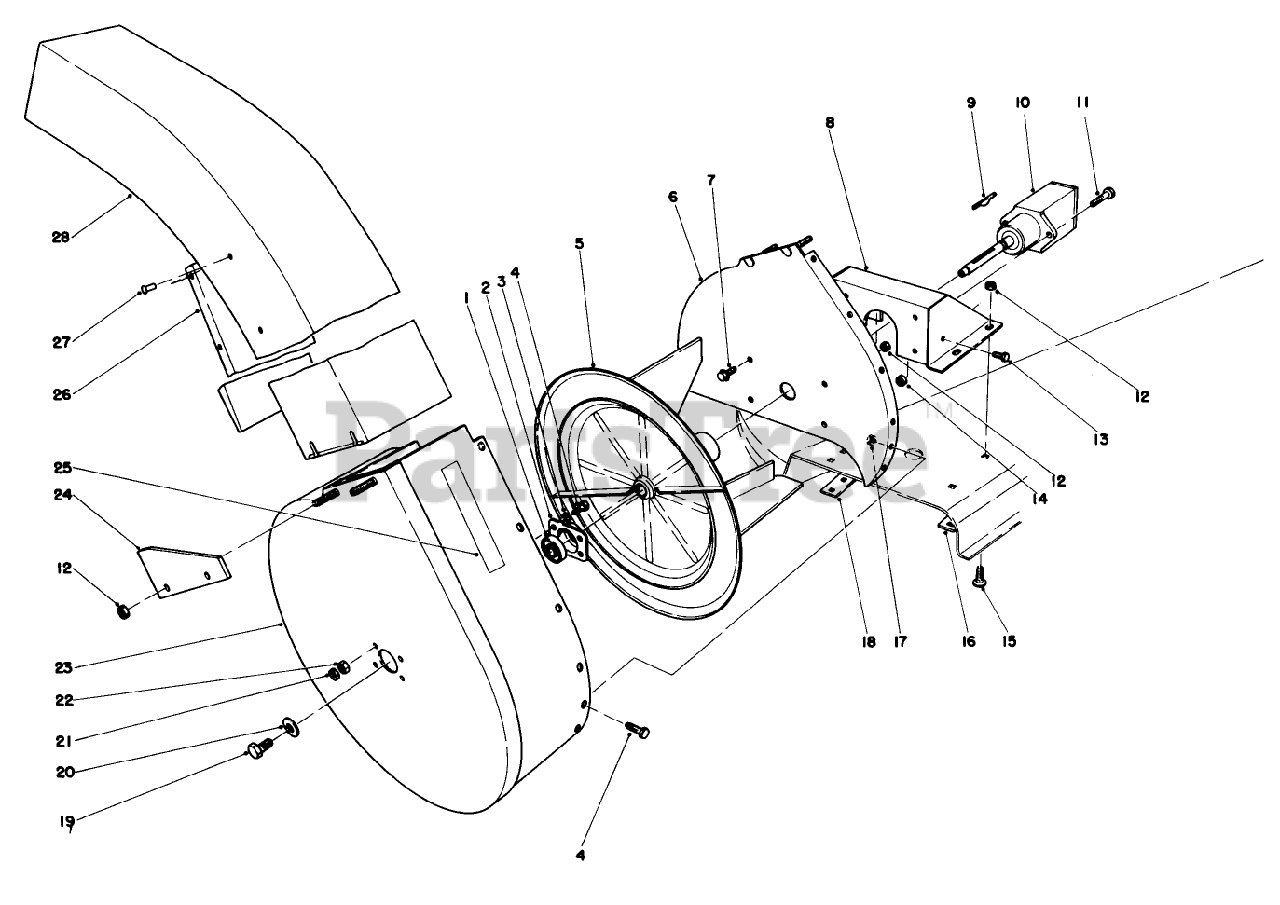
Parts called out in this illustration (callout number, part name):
1	BEARING-BALL
2	CUP-BEARING
3	WASHER-LOCK
4	SCREW-HH
5	IMPELLER W A BO
6	MTG PLATE WA B
7	SCREW-HHF
8	GEAR BOX BRKT WA B
10	GEAR BOX ASM
11	SCREW-HH
12	NUT-LOCK, CONE
13	SCREW-HH
14	NUT-LOCK, CONE
15	BOLT-CARR
16	Plate-Bracket R.H.
17	NUT-LOCK, CONE
18	Plate-Bracket
19	CAPSCREW 3/8 16 3/4
20	SPACER
21	NUT-JAM
22	NUT-HEX
23	Housing-Blower (Incl. Ref. #24)
24	Bracket
25	Decal-Waming
26	Deflector-Chute
28	Chute Assembly (Incl. Ref. #26 & 27)
